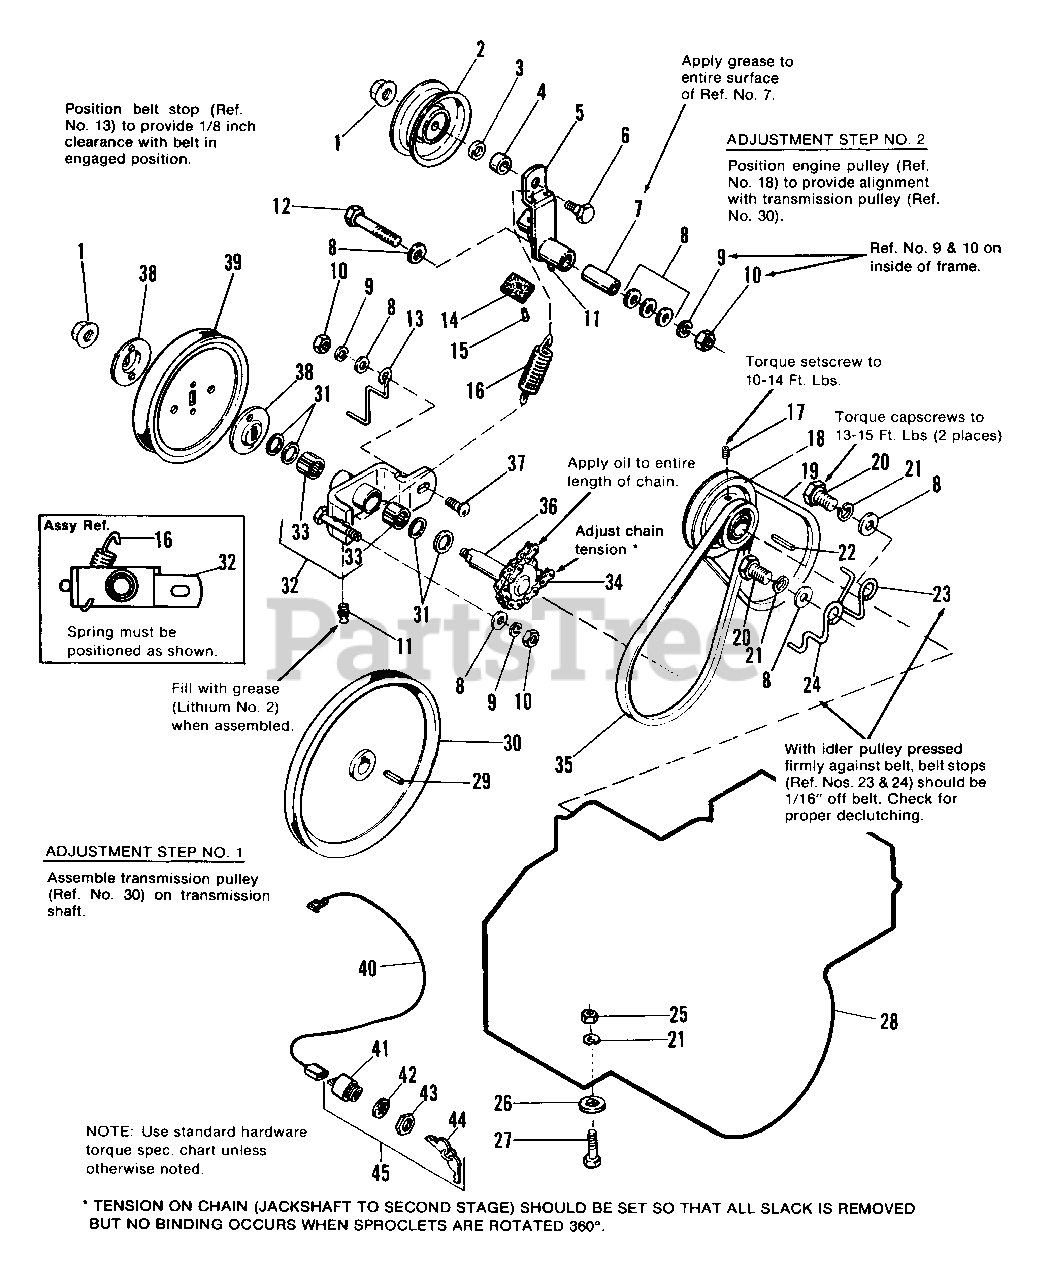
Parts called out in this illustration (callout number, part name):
1	LOCKNUT, Hex, Flange, Whiz, 3/8-16
2	PULLEY, Idler
3	SPACER, Inner Race
5	LEVER & BRAKE ASSY. (Includes Ref. Nos. 11, 14 & 15)
6	CAPSCREW, Hex Hd., 3/8-16 x 1-1/4
8	WASHER, Plain, 5/16
9	LOCKWASHER, 3/8
10	NUT, Hex, Full, 3/8-16
11	FITTING, Grease
12	CAPSCREW, Hex Hd., 3/8-16 x 2-1/2
13	STOP, Belt
14	PAD, Brake
15	RIVET, #7 x 3/8, Brass
17	SETSCREW, 5/16-18 x 3/8
18	PULLEY, Engine
19	V-BELT, 40"
20	CAPSCREW, Hex Hd., 5/16-24 x 3/4
21	LOCKWASHER, 5/16
22	KEY
23	STOP, Belt
24	STOP, Belt
25	NUT, Hex, Full, 5/16-18
26	WASHER, Special (828 & 1028)
27	CAPSCREW, Hex Hd., 5/16-18 x 1-1/2 (524 Only)
30	PULLEY, Transmission
31	SPACER, Washer
32	HOUSING ASSY. (Includes Ref. Nos. 11 & 33)
33	BEARING, Roller
34	CHAIN, W/Connecting Link (Jackshaft to Second Stage)
36	SHAFT ASSY., Sprocket (Jackshaft)
37	BOLT, Carriage, 3/8-16 x 1-1/4
38	WASHER, Special
39	PULLEY (Jackshaft)
40	WIRE ASSY.
42	LOCKWASHER, Int., 5/8
43	NUT, Hex, 5/8-32
44	KEY & RING ASSY.
45	SWITCH, Key
